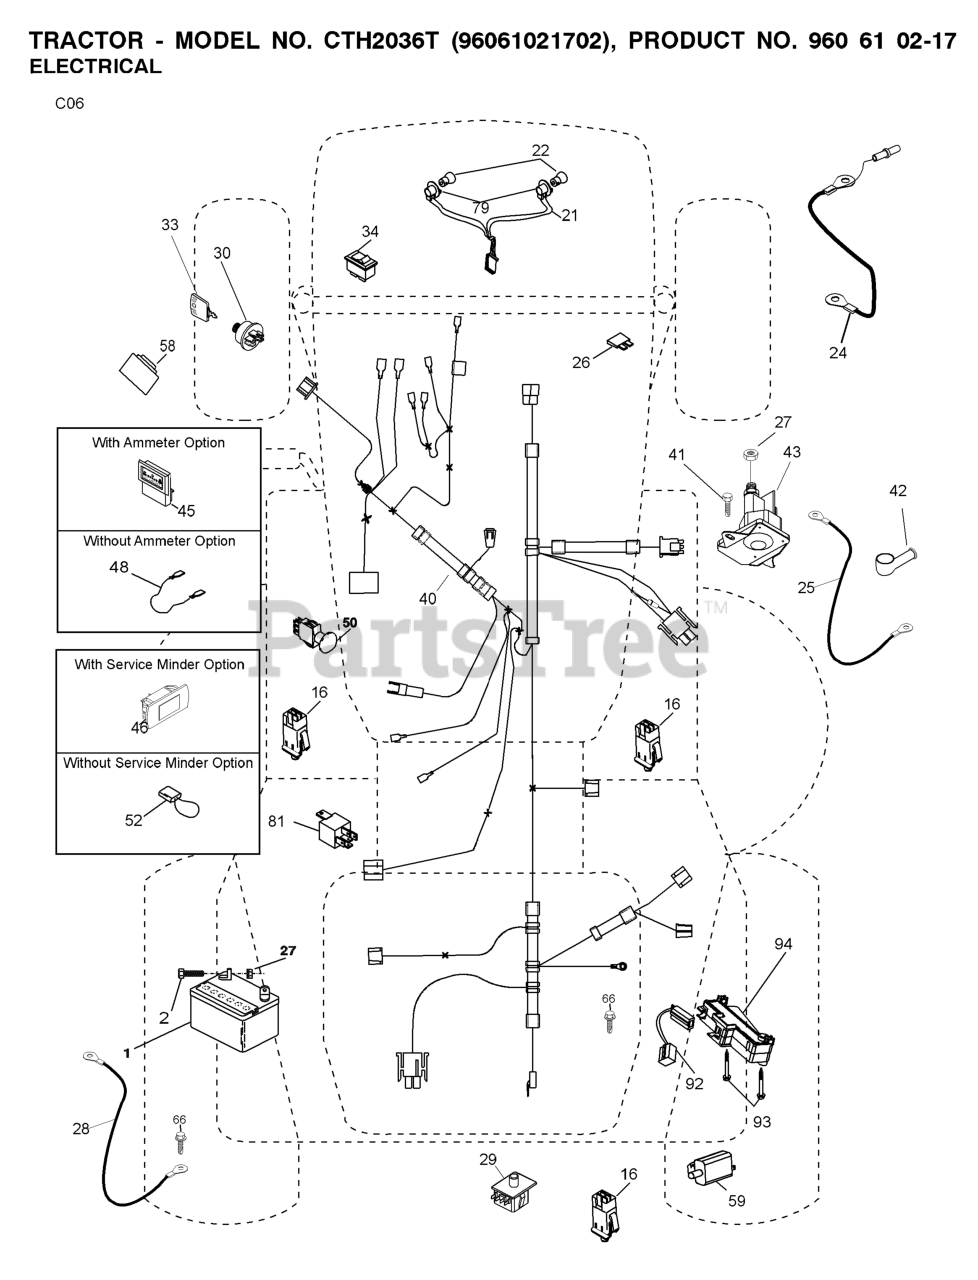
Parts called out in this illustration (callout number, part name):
1	Battery 12 Volt 25 Amp
2	BOLT.HEX.1/4.X.3/4.DICHROMATE
16	SWITCH INTERLOOK PUSH-IN
21	HARNESS ASSY LIGHT
24	CABLE.BATTERY.6GA.16"RED
25	CABLE BATTERY
26	FUSE 20AMP
27	NUT
28	CABLE GROUND
29	SWITCH.SEAT.DP W/RAMPS
30	SWITCH.IGN.DELTA.W.LGH.ROS
33	KEY.CHAIN.BLISTER.PACK.GEN.INT
40	RP HARNESS.IGN.ELECT.REG.CRD
41	BOLT
42	TERMINAL COVER
43	SOLENOID.W/BRASS.PLUNGER
46	RP.GUAGE.SRVCMNDR.HRMTR.
48	ADAPTER.AMMETER
50	RP.PTO.SWITCH.8 TERMINAL.BLACK
58	BUZZER
59	.WITCH.FULL BAGGER.INDICATOR
79	BULB HOLDER ASM.
81	RELAY.ASSY.T
92	HARNESS.PIGTAIL.CONSLE
93	SCREW.PLASTITE
94	MODULE.REVERSE.ROS
101	PIGTAIL.MATNLK.NEW.HAR
